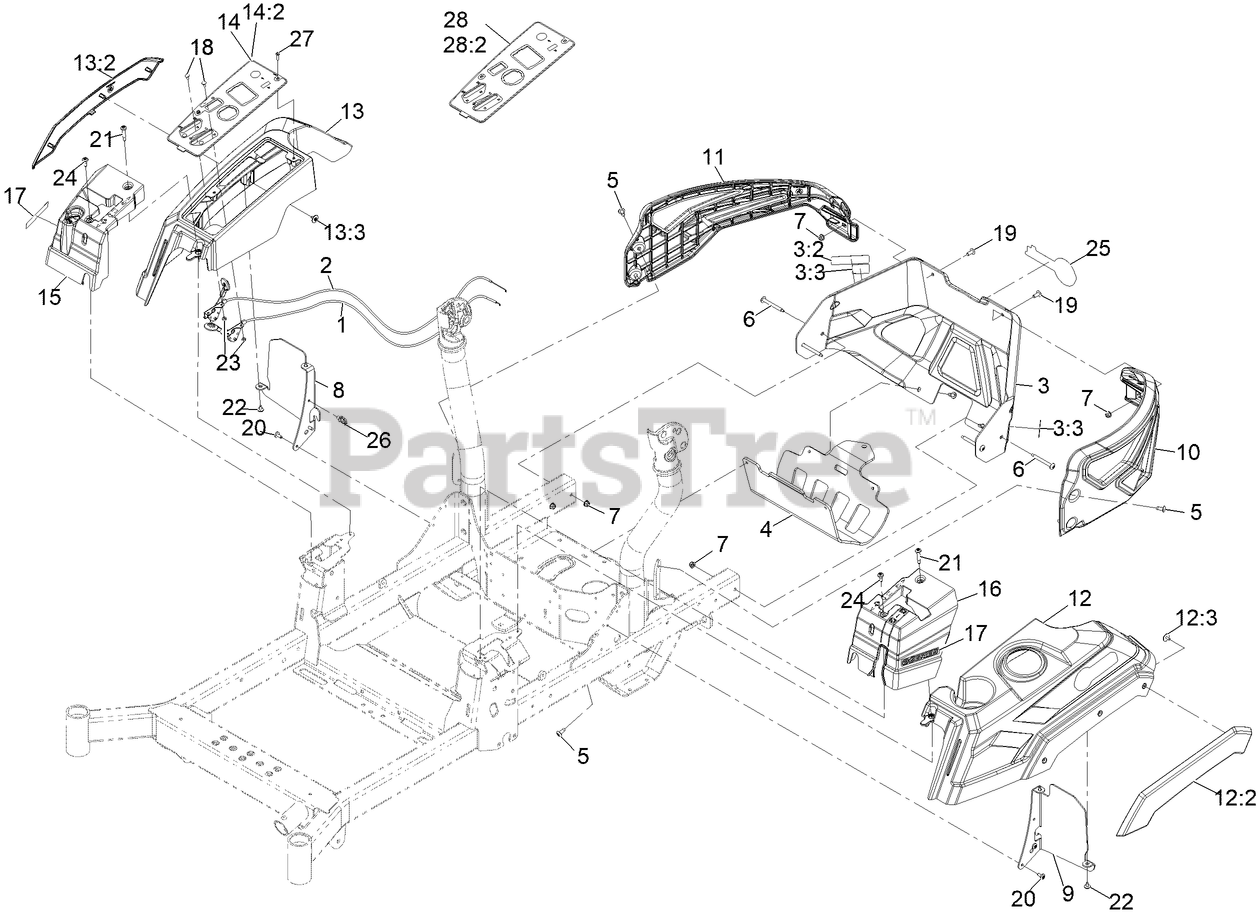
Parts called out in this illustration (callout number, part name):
1	CABLE-CONTROL, THROTTLE
2	CABLE-CONTROL, CHOKE
3	ASM, Rear Guard W/ Decals
3:2	DECAL-ARRESTOR, SPARK
3:3	DECAL-WARNING
4	Guard, Muffler
5	SCREW, TAPTITE
6	SCREW-TORX
7	NUT-HF, NI
8	Bracket, Pod, Rt
9	Bracket, Pod, Lt
10	GUARD, UPPER, LT
11	GUARD, UPPER, RT
12	ASM, Pod Lt
12:2	Fender, Lt
12:3	Screw-Torx
13	ASM, POD RT
13:2	Fender, Rt
13:3	Screw-Torx
14	ASM-Control Panel W/Decal
14:2	DECAL-CONTROL PANEL
15	Cover, Motion Control, Rt
16	Cover, Motion Control, Lt
17	DECAL-E-SERIES
18	BOLT-CARR
19	SCREW-TORX
20	SCREW-TORX
21	SCREW-SHOULDER
22	SCREW-TORX
23	NUT-LOCK, NI
24	SCREW-SHOULDER
25	DECAL, EXMARK LOGO
26	CLIP-TIE
27	Screw-Plastic, HWH
28	ASM-Control Panel W/Decal
28:2	Decal-Control Panel
